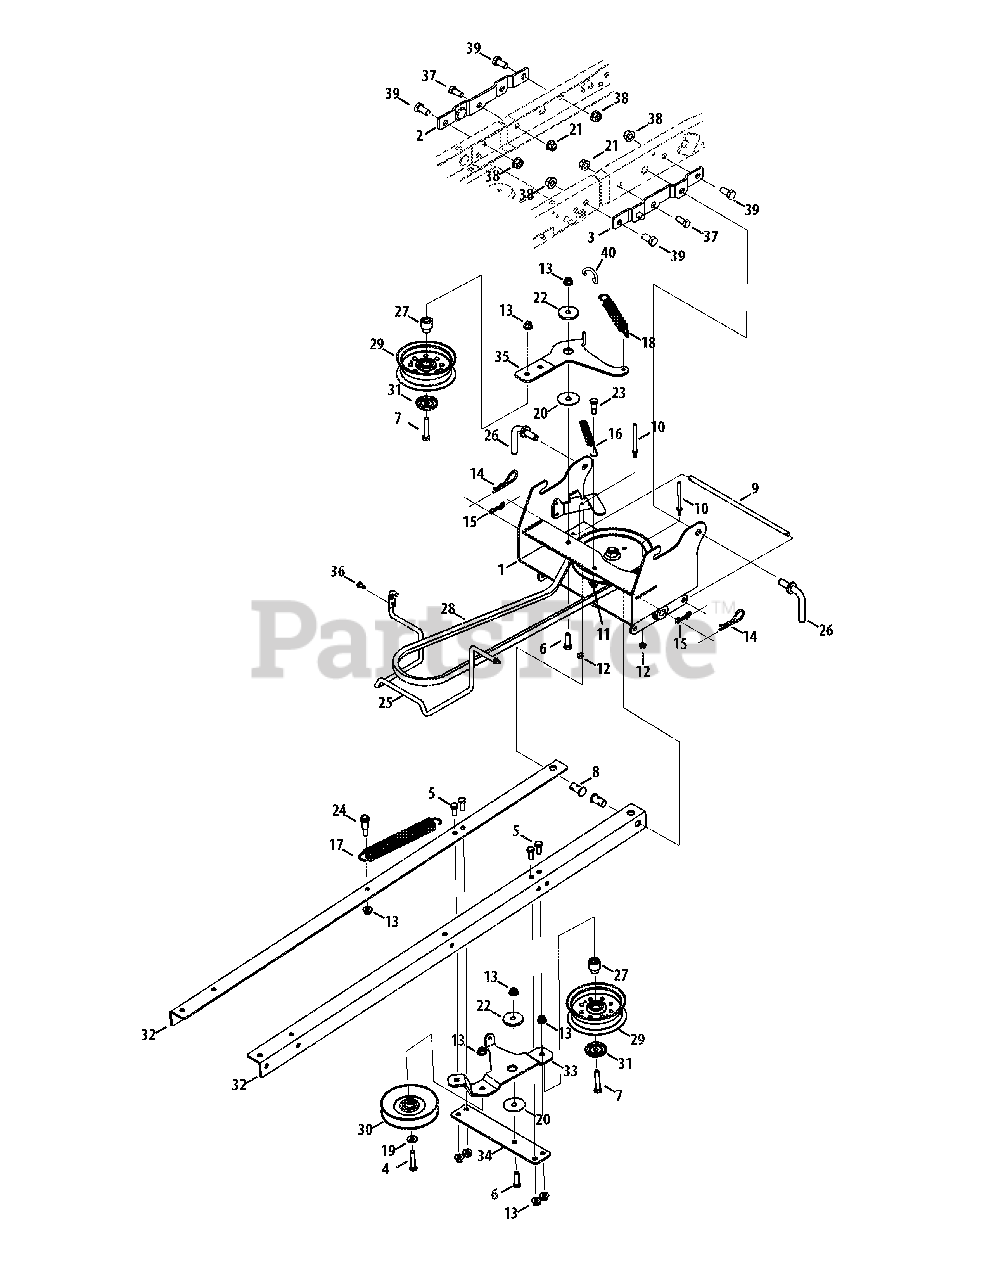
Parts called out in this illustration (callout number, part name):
1	Spindle Housing
1	Spindle Hanger Bracket
1	Hex Washer Screw, 5/16-18 x .750
2	Bracket Assembly, Hanger, Right
3	Bracket Assembly, Hanger, Left
4	Hex Screw, 3/8-16, 1.75, Gr5, Std
5	Hex Screw, 3/8-16, .880, Gr5, Std
6	Hex Screw, 3/8-16, 1.25, Gr5, Std
7	Hex Screw, 3/8-16, 2.00, Gr5, Std
8	Pin, Clevis, .62 Dia.
9	Shaft, .375Od x 12.3450 Lg
10	Keeper, Belt, .25 Dia x 3.0
11	Nut, Flange Lock, 5/16-18, Grf, Nylon
12	Nut, Flange Lock, 1/4-20, Grf, Nylon
13	Nut, Flange Lock, 3/8-16, Grf, Nylon
14	Pin, Cotter, Int, .148 x 3.00
15	Pin, Cotter, Bow-Tie 91
16	Spring, Extension, .53 Dia x 4.75 Lg
17	Spring, Extension, 1.25 OD x 8.5 Lg.
18	Spring, Extension, 5.30 Lg
19	Washer, Flat, .385 x .870 x .092
20	Washer, Thrust, .445 x 1.92 x .060
21	Nut, Flange Lock, 1/2-13, Grf, Nylon
22	Spacer, Shoulder, .8840 x .190
23	Screw, Shoulder, .437 Dia. x .54
24	Bolt, Shoulder, .50 x .925, 3/8-16
25	Rod, Keeper, Engine Pulley
26	Rod, Lock, .500
27	Spacer, Shoulder, Idler Pivot
28	Belt, V-type, Bsec, 68.2
29	Pulley, Idler, 4.50" Dia
30	Pulley, Idler, 5.06 Dia
31	Cap, Pulley, Hd
32	Bracket, Link
33	Bracket, Idler, Pivot
35	Bracket, Idler, Pivot
36	Screw, M6-1 x .625"
37	Hex Screw, 7/16-14, 1.00, Gr5, Std
38	Nut, Flange Lock, 7/16-14
39	Hex Screw, 1/2-13, 1.00, Gr5, Std
40	Hook, Rod, Spring
